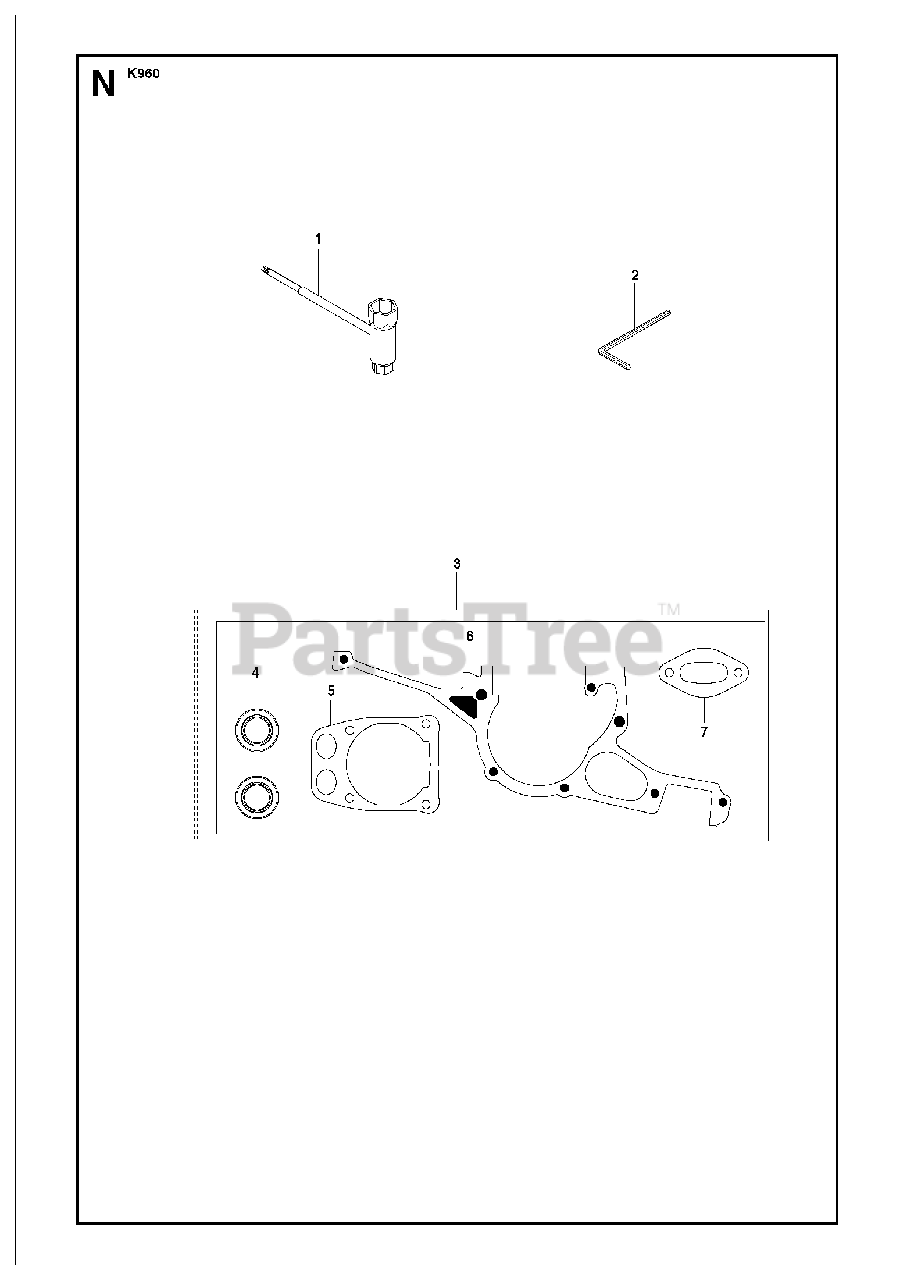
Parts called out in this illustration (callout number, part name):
3	GASKET KITIncl. 9 - 12
4	SEALING RING
5	GASKET
6	GASKET
7	GASKET
